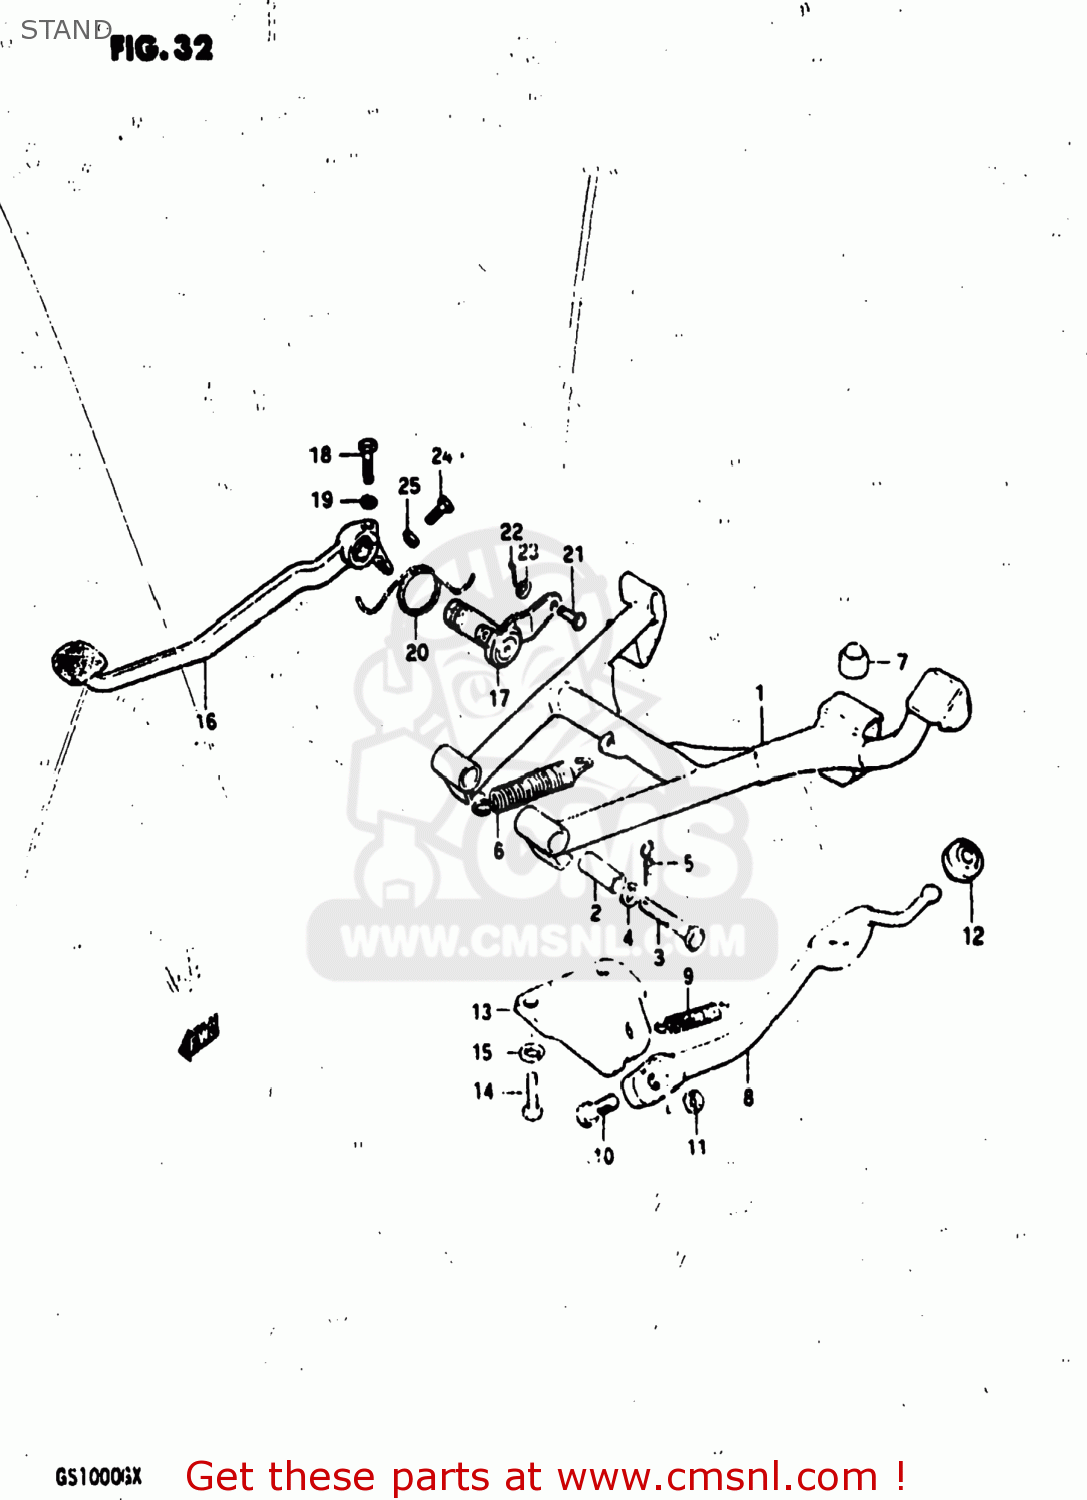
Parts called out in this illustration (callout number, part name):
1	STAND,CENTER
2	SPACER(10X16X38.8)
3	BOLT
4	LOCK WASHER
5	CLIP
6	SPRING
7	CUSHION
8	STAND,PROP
9	SPRING
10	BOLT(10X30)
11	NUT
12	CUSHION
13	BRACKET,SIDE STAND
14	BOLT
15	LOCK WASHER
16	PEDAL,BRAKE
17	ARM,BRAKE PEDAL
18	BOLT
19	LOCK WASHER
20	SPRING
21	PIN
22	PIN
23	WASHER
24	BOLT
25	NUT
